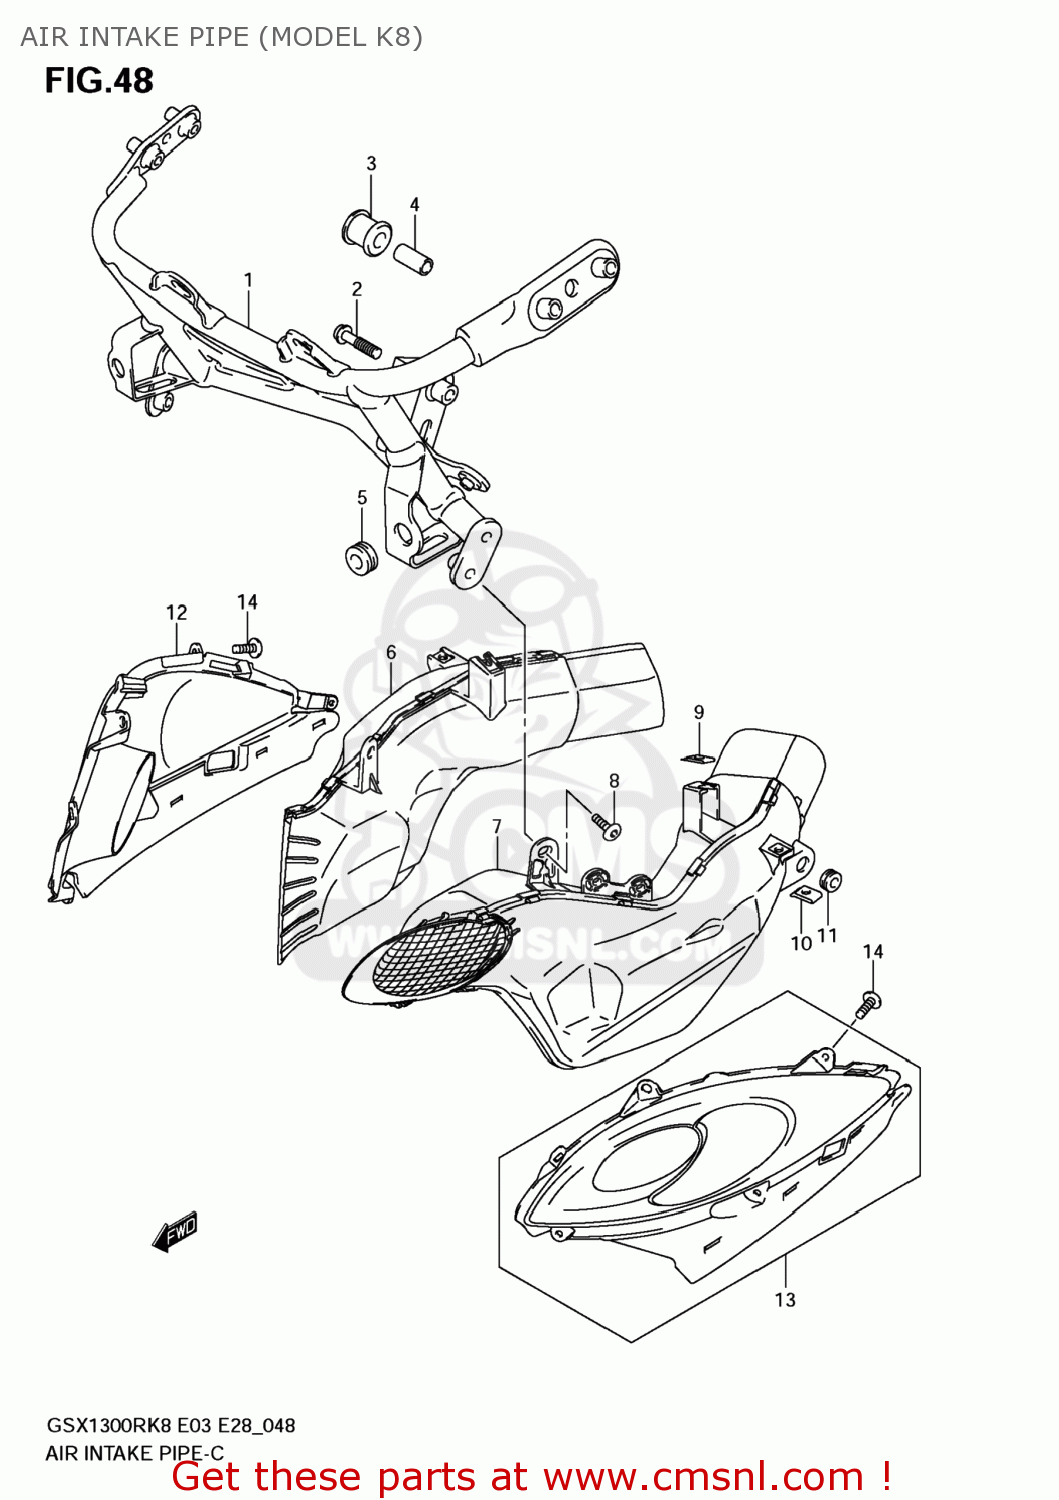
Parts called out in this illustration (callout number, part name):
1	BRACE,COWLING
2	BOLT(8X40)
3	CUSHION,COWLING BRACE
4	SPACER(8.6X12.2X26.5)
5	CUSHION
6	PIPE COMP,AIR
7	PIPE COMP,AIR
8	SCREW,INTAKE PIPE & BRACE
9	NUT,COWL
10	NUT
11	CUSHION
12	COVER COMP,INT
13	COVER COMP,INT
14	SCREW
